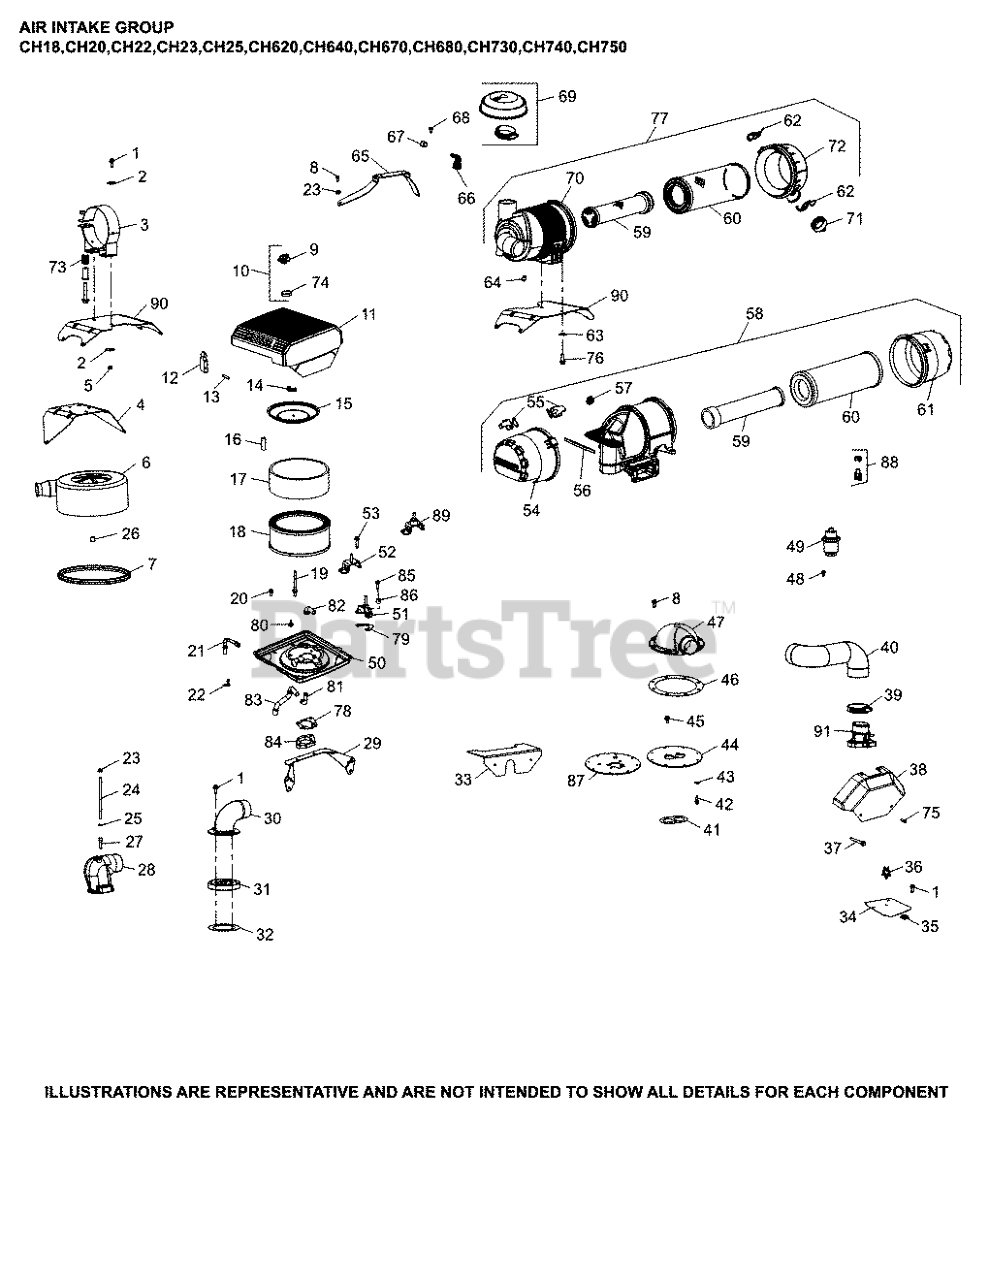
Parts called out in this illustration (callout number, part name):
9	KNOB, COVER
10	KIT, KNOB W/SEAL
11	KIT, AIR CLEANER COVER
11	COVER, AIR CLEANER
12	SEAL, INNER AIR CLEANER
14	NUT, WING
15	COVER, INNER AIR CLEANER
17	ELEMENT, PRECLEANER (LOW)
18	ELEMENT, AIR CLEANER - Also available Retail Packaged 47 883 03-S1 Air Filter Kit
20	SCREW, FLG THD FRM M6X1.0X16
29	BRACKET, AIR CLEANER BASE
48	SCREW, THREAD FORMING
50	KIT, AIR CLEANER BASE
52	BRACKET, AIR CLEANER
78	GASKET, AIR CLEANER BASE
80	PLUG, HOLE
